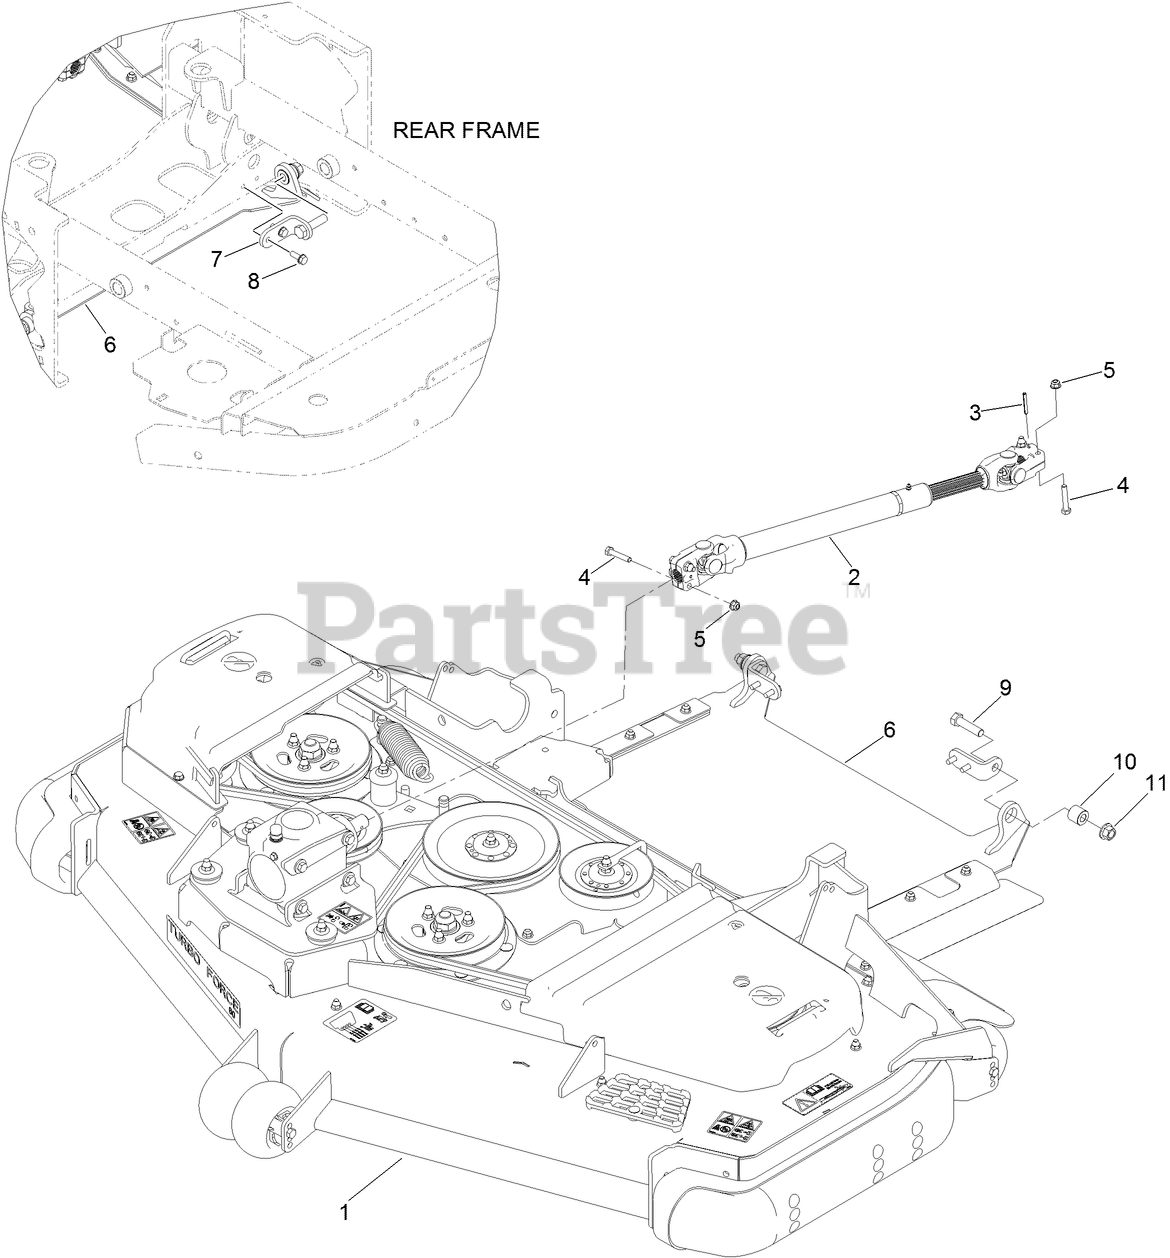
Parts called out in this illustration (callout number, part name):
1	DECK ASM
2	DRIVESHAFT ASM
3	PIN-ROLL
4	SCREW-HH
5	NUT-HF, NI
6	DISCHARGE TUNNEL ASM
7	BRACKET-DISCHARGE
8	SCREW-TAPTITE
9	SCREW-HH
10	BUSHING-SLEEVE
11	NUT-LOCK
